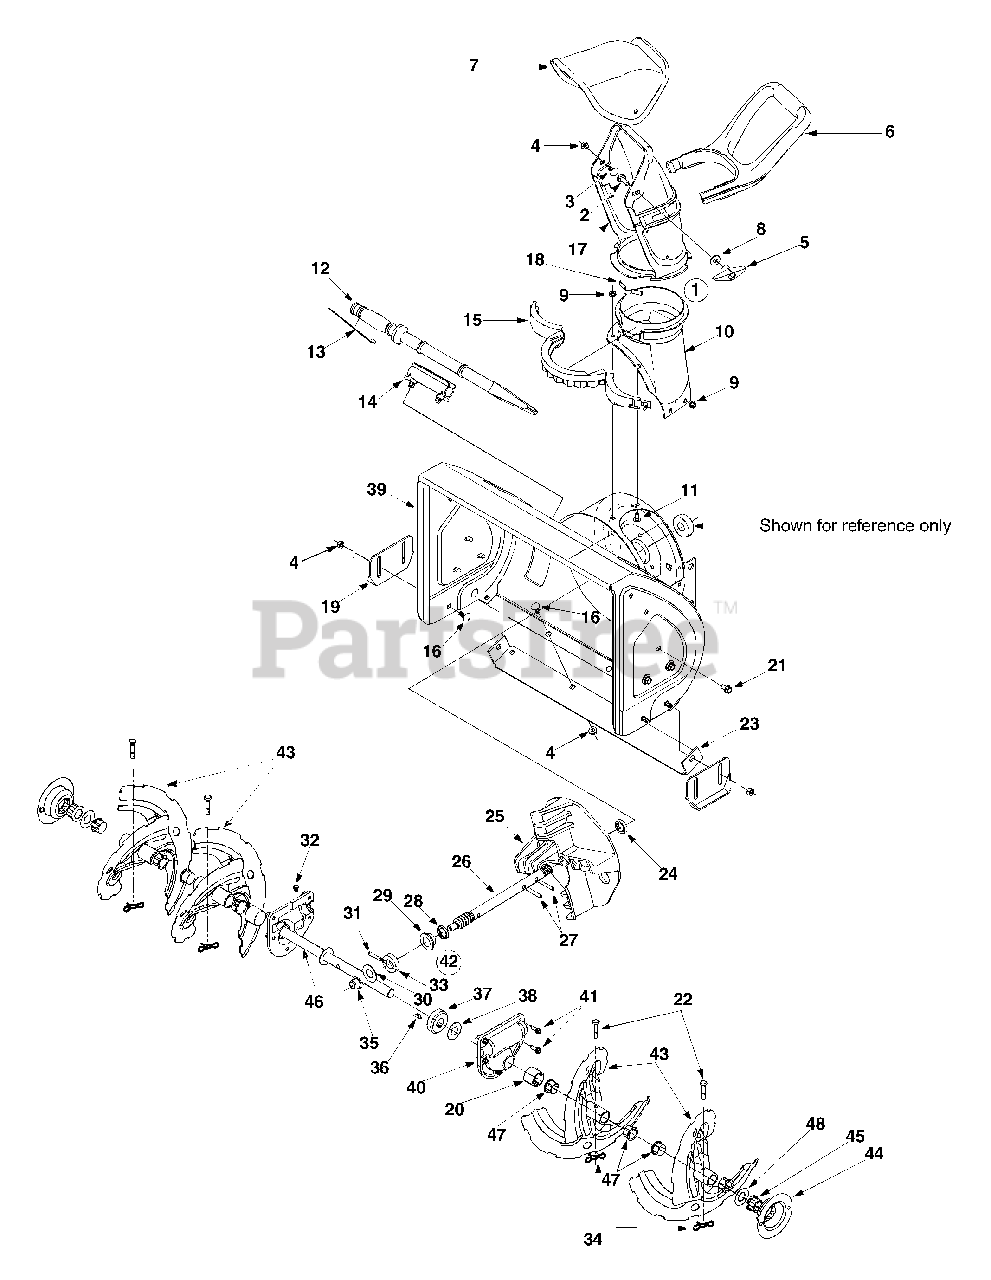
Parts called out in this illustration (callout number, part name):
1	Chute Assembly
2	Carriage Bolt 5/16-18 x 1.0"
3	Carriage Bolt 5/16-18 x 0.750"
4	Flange Lock Nut, 5/16-18
5	Chute Knob Assembly
6	Chute Handle
7	Upper Chute
8	Washer
9	Flange Lock Nut, 1/4-20
10	Chute Adapter
11	Carriage Screw 1/4-20 x 0.62"
12	Clean-out Tool
13	Cable Tie
14	Clean-out Tool Mount
15	Lower Chute Ring
16	Carriage Bolt 5/16-18 x 0.75"
17	Lower Chute
18	Chute Adjuster Spring
20	Spacer, 1.25OD x.75ID x 1.00 Lg.
21	AB Screw 5/16-12
22	Shear Pin,.25 x 1.50
24	Spacer
25	Impeller
26	Worm Shaft
27	Spiral Pin
28	Oil Seal
29	Flange Bearing
30	Flat Washer,.51 x 1.12 x.06
31	Spiral Pin
33	Thrust Collar
34	Bow Tie Cotter Pin
35	Flange Bearing
36	Key
37	Worm Gear 20T
38	Flat Washer
41	TT Screw 1/4-20 x 0.75"
42	Auger Gearbox Assembly
45	Hex Flange Bearing
46	Auger Axle
47	Flange Bushing
48	Flat Washer
